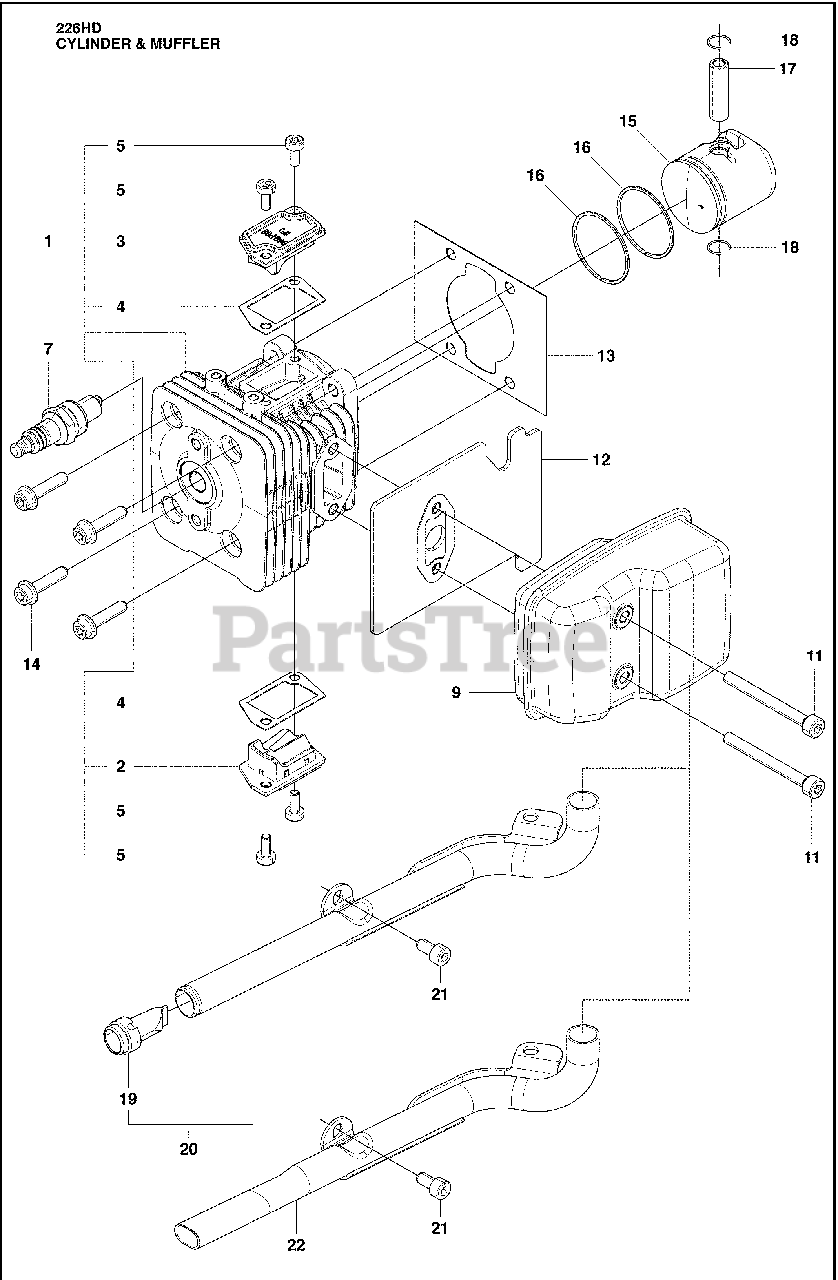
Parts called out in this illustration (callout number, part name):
1	Cylinder, Complete
2	Cover, TR S
3	Cover, TR F
4	Gasket, TR
5	Bolt
7	Spark Plug, CMR7H BLYB
11	Bolt
13	Base Gasket
14	Torx Bolt
20	EXHAUST PIPE
21	Bolt, M5 X L10
